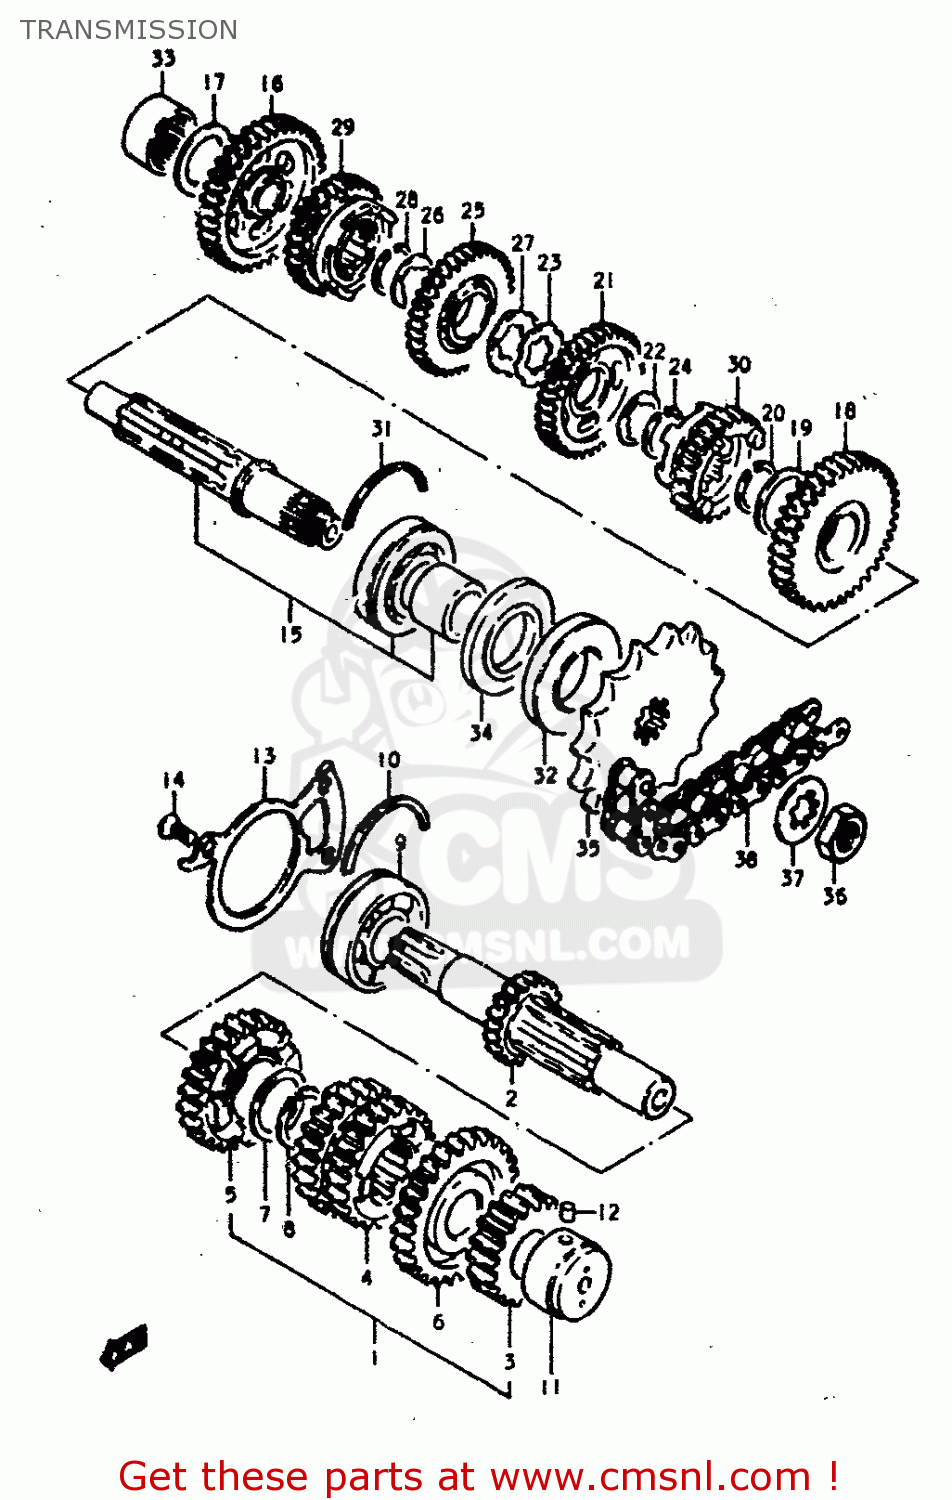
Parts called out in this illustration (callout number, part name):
1	SHAFT,COUNTER
2	SHAFT,COUNTER
3	GEAR,2ND DRIVE(NT:18)
4	GEAR,THIRD DRIVE
5	GEAR,FIFTH DRIVE
6	GEAR,SIXTH DRIVE
7	WASHER
8	CIRCLIP
9	BEARING(25X62X17)
10	C-RING
11	ROLLER BEARING (20X34X2
12	PIN
13	PLATE,COUNTERSHAFT BEARING
14	SCREW
15	SHAFT,DRIVE
16	GEAR,FIRST DRIVEN
17	WASHER
18	GEAR,SECOND DRIVEN
19	WASHER
20	CIRCLIP
21	GEAR,THIRD DRIVEN
22	WASHER,LOCK
23	WASHER,LOCK
24	CIRCLIP
25	GEAR,FOURTH DRIVEN
26	WASHER,LOCK
27	WASHER
28	CIRCLIP
29	GEAR,5TH DRIVEN(NT:25)
30	GEAR,SIXTH DRIVEN
31	C-RING
32	OIL SEAL
33	ROLLER BEARING (20X34X1
34	SEAL,OIL(32X62X5.5)
35	SPROCKET,ENGINE(NT:16)
36	NUT
37	WASHER
38	CHAIN ASSEMBLY,DRIVE
